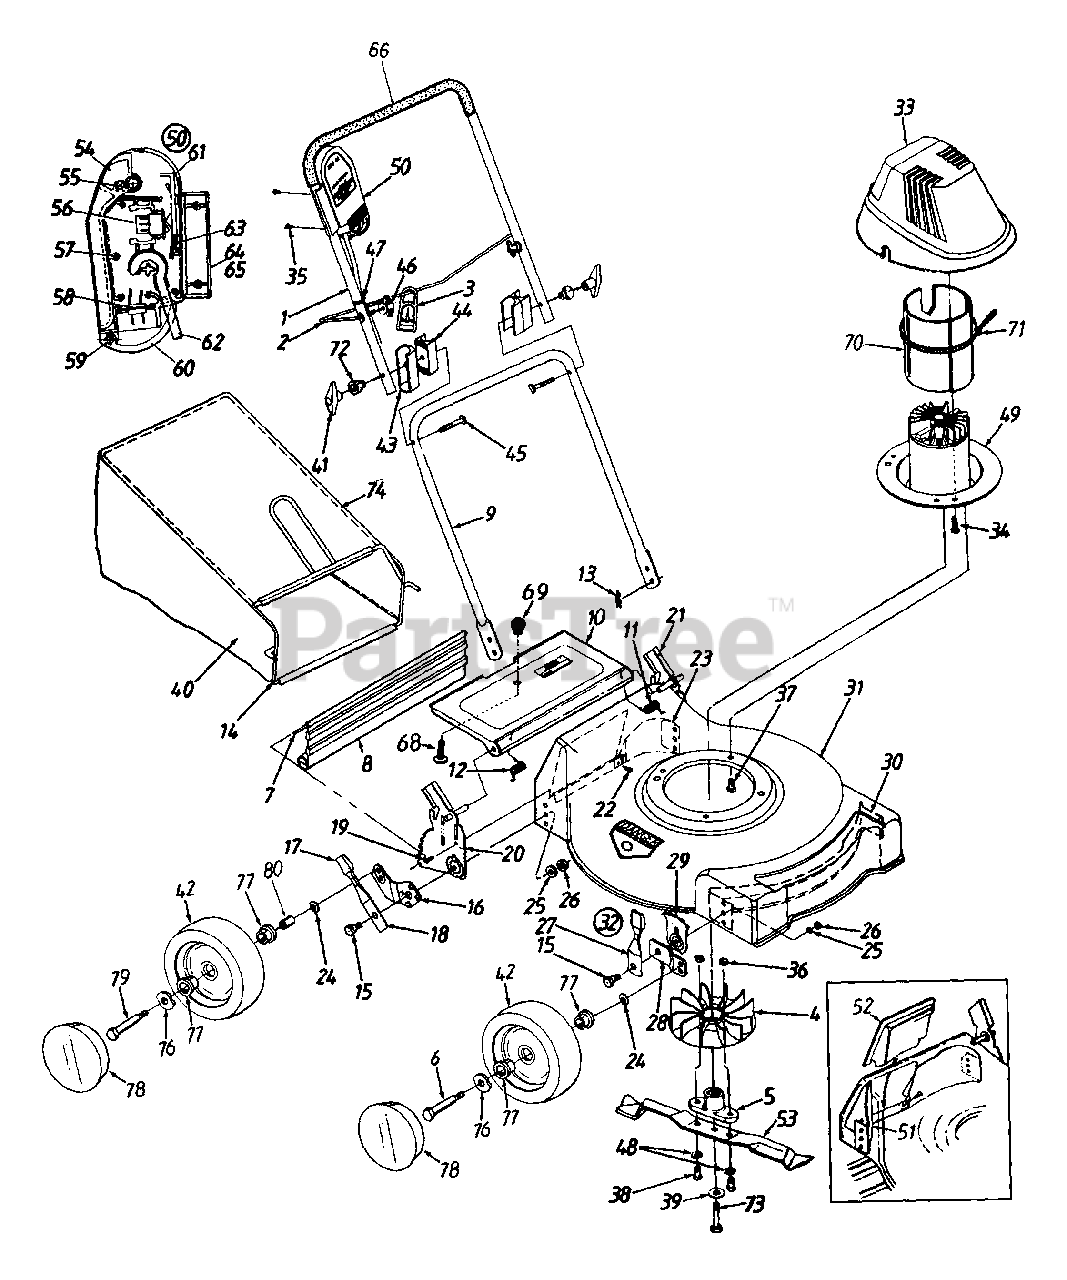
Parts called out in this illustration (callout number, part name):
3	Strain Relief - Cord
5	Blade Adapter
6	Front Axle Bolt
7	Rear Flap Wire
12	Door Spring - R.H.
13	Hairpin Clip
16	Pivot Bar - R.H.
17	Spring Lever Knob
19	Hex L-Wash. Hd. AB-Tap Scr. 1/4 x .62" Lg.
20	Handle Brkt. Ass'y. - R.H.
21	Handle Brkt. Ass'y. - L.H.
22	Torx . Mach. AB-Tap Scr. 1/4 x .62" Lg.
25	Bell-Wash. .39" I.D. x 1.38" O.D.
26	Hex Nut 3/8-16 Thd.
27	Spring Lever Ass'y. w/Knob
29	Height Adj. Plate
34	Scr. #10-16 x .75" Lg.
35	Self-Tap. Scr. #7 x 1" Lg.
36	Hex Nut 3/8-24 Thd.
37	Hex L-Wash. TT-Tap Scr. 3/8-16 x .75" Lg.
38	Hex Bolt 3/8-24 x 1.25" Lg.
39	Bell-Wash. .396" I.D. x 1.14"
41	Plastic Knob
42	Wheel Ass'y. Comp.
43	Upper Handle Insulator
44	Lower Handle Insulator
45	Carriage Bolt 5/16-18 x 3" Lg
46	Wing Nut 1/4-20 Thd.
48	Bell-Wash. 3/8" I.D.
49	Motor, Cord & Switch Ass'y.
50	Cord & Switch Ass'y. Comp.
53	19" Mulching Blade
54	Handle - Switch Actuator
55	Spring - Switch Handle
56	Switch
57	Screw #6-32 x .5" Lg.
58	Plug Ass'y.
59	Retainer Plug Spring
60	Retainer Plug
62	Cord Ass'y.
63	Spring Latch
64	Housing - Upper Half
66	Foam Grip
68	Truss Scr. #10-24 x .38" Lg.
71	Cable Tie
72	Insulator Knob
73	Hex Bolt 3/8-24 x 2.5" Lg.
77	Ball Bearing
78	Hub Cap
79	Rear Axle Bolt
80	Spacer
